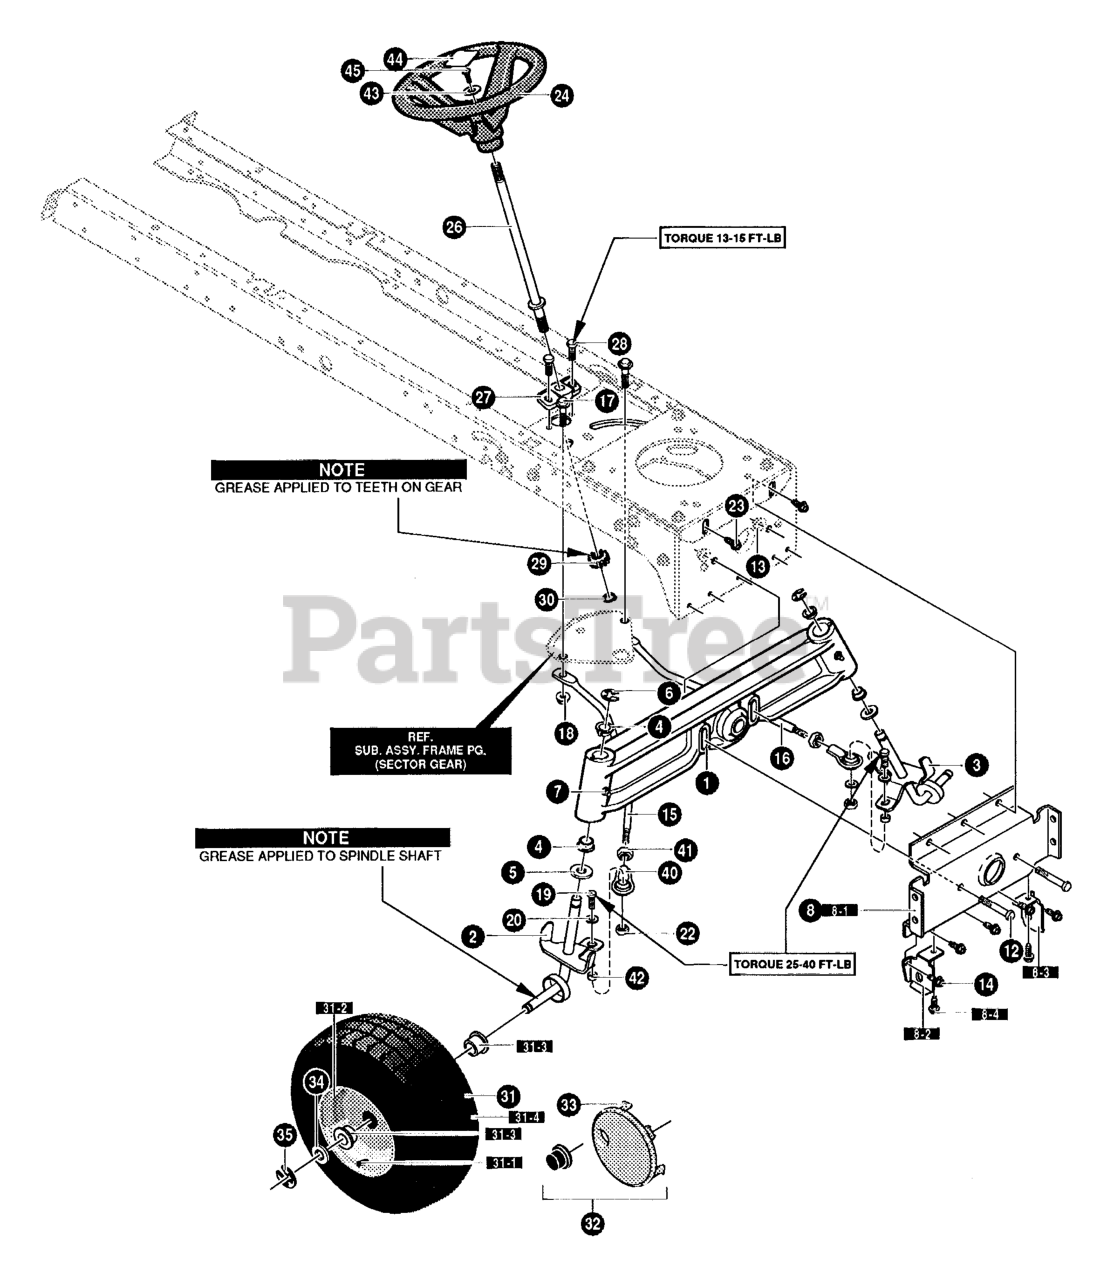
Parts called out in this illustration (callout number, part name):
1	AXLE, FRONT ASSEMBLY
2	SPINDLE, RH
3	SPINDLE, LH
4	BEARING, SPINDLE
6	E- RING
7	ZERK, GREASE FITTING
8	FRONT AXLE/DECK HANGER
8-1	HANGER, AXLE
8-2	HANGER, DECK RH
8-3	HANGER, DECK LH
8-4	SCREW, 5/16-18 x 0.75
12	SCREW, 5/16-24 x 2.75
13	NUT, 5/16- 24
14	SCREW, 5/16-18 x 0.75
15	ROD, DRAG LINK
16	ROD, DRAG LINK
18	NUT, 3/8- 16
20	WASHER, FLAT
22	NUT, 3/8- 16
23	SCREW, 5/16-18 x 0.75
24	STEERING WHEEL
26	SHAFT, STEERING
27	BEARING- LOWER
28	SCREW, 5/16-18 x 0.75
29	GEAR, PINNION
30	RING, RET
31	TIRE & RIM 15X6-6
31-1	VALVE STEM
31-2	RIM, CARLISLE
31-3	BEARING
31-4	TIRE, 15X6X6
32	HUB CAP
33	CLIP, HUB CAP
35	"E" RING
40	TIE ROD
41	NUT 1/2-20
42	SPACER, SLEEVE
43	FLATWASHER
44	INSERT, STEERING WHEEL
